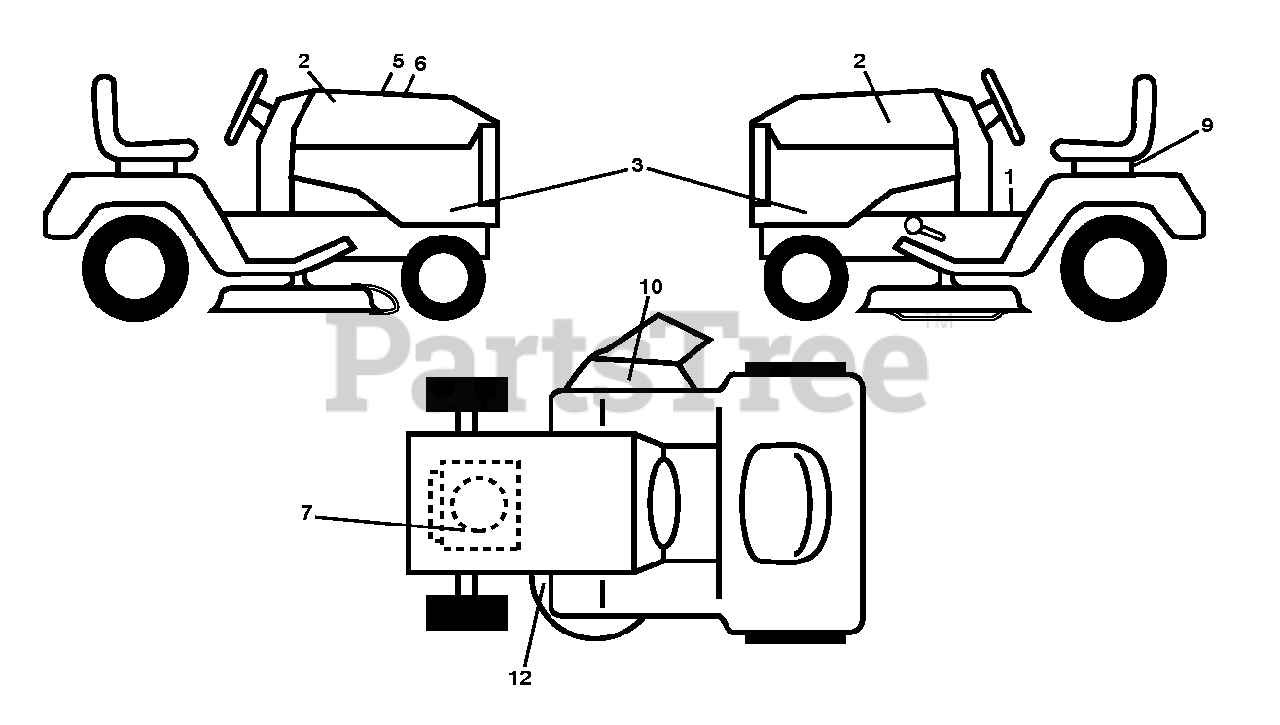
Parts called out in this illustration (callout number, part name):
1	DECAL.FENDER.WARNING.ENGLISH
2	DECAL.BADGE.170MM.TEXTLOGO.
3	DECAL TRACTOR SIDE PANEL SDPNL
5	DECAL.WARNING.CUST.RESP.E85.
6	DCL.RPL.BSM44.INTK.TLW.46.K46
7	DECAL.ENG.BS.22INTK.DOM.381708
9	DECAL BTRY SYMBOLS
10	DECAL, DECK DEFLECTOR, WARNING
12	DECAL.V-BELT.SCH.42/46"MEC/ELE
